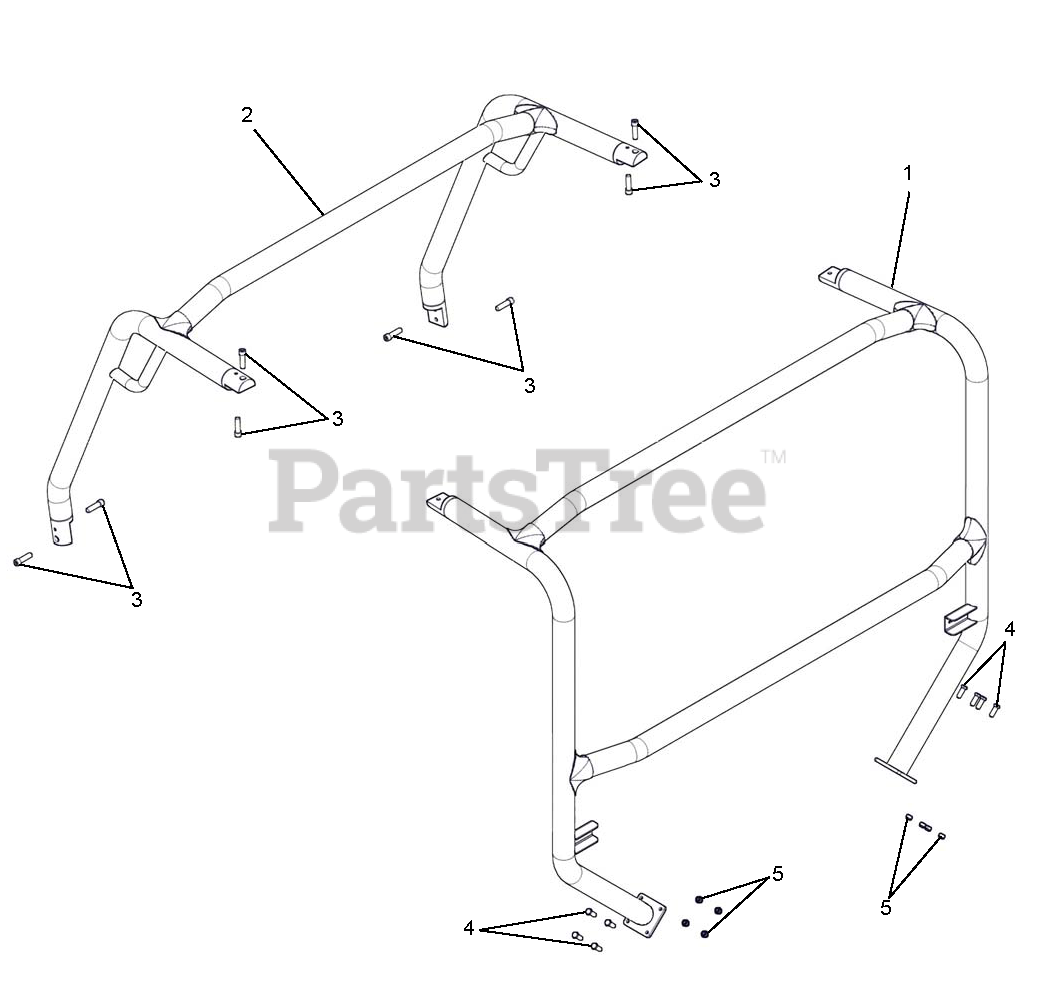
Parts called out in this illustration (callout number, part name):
1	ROPS WLDT, TREKER REAR
2	ROPS WLDT, TREKER FRONT
3	HSHCS 3/8-16X1.5 GR5
4	@BLT-HEX .31-18X1.00 GR5 YWZC
5	@NUT-LK-NYL .312-18 YWZC
